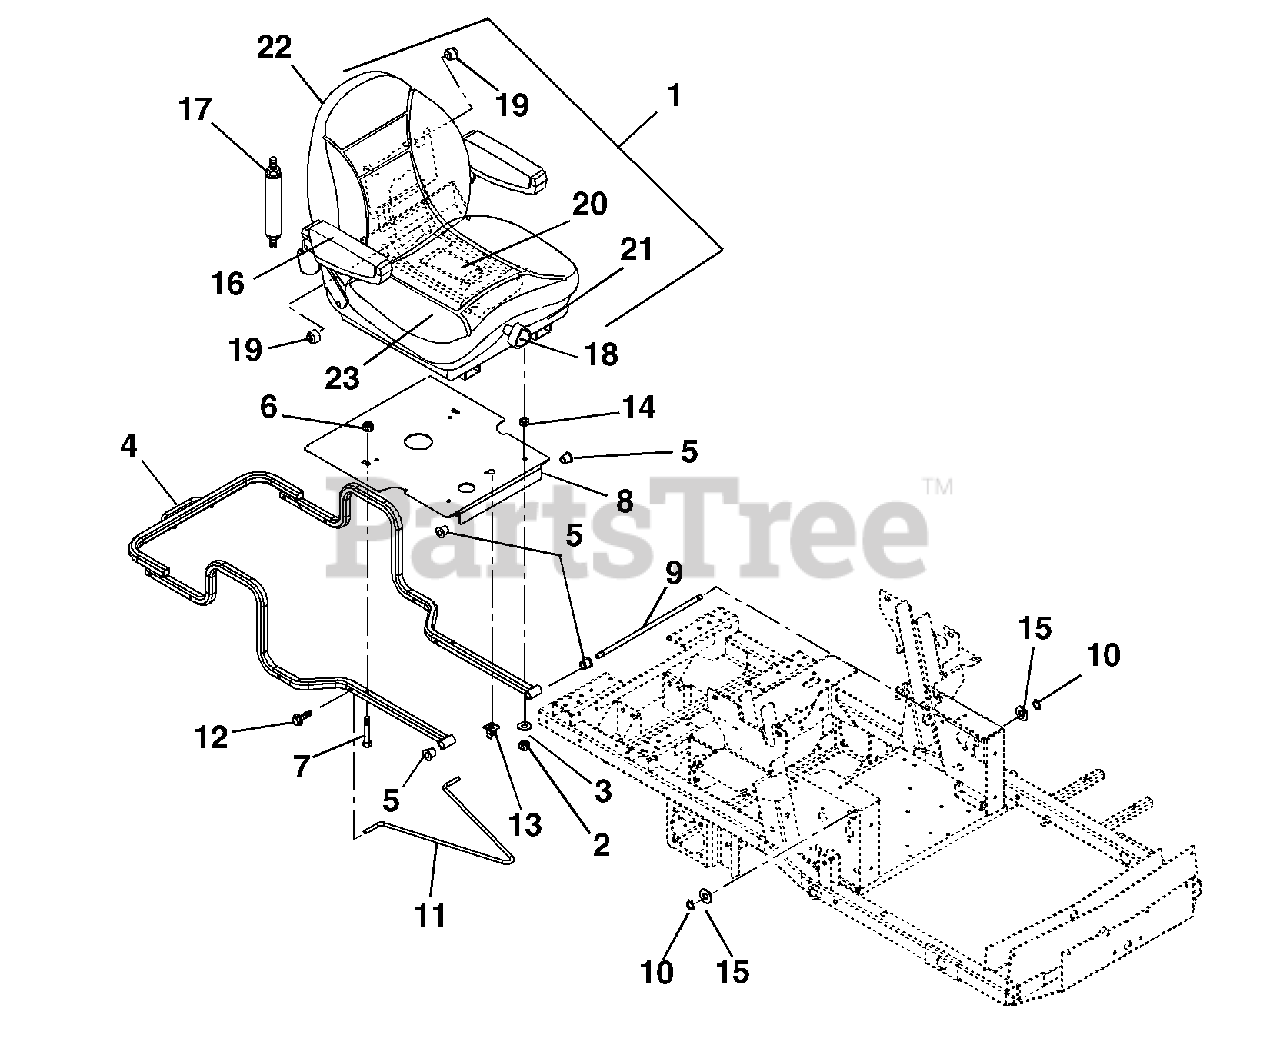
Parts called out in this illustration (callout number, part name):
1	Seat-Suspension
2	Nut-Locking-Nylon M8-1.25
3	Washer-Flat-Steel .38 x .875 x .083
4	Weldment, Hood Frame
5	Bushing-Flange .515 x .750 x .745 x 1.00
6	Nut-Locking-Top-Flange .38-16
7	Bolt-Rib Neck .38-16 x 1.50
8	Weldment, Seat Pivot Mount
9	Rod-Seat Frame Pivot
10	Ring-Retaining-External .500 x .050
11	Rod-Prop
12	Screw-Tapping .25-20 x .50 Hex Washer Head
14	Bushing-Sleeve .377 x .624 x .235
15	Washer-Flat-Steel .531 x 1.06 x .095
16	Kit-Arm Pad (1 per bag)
17	Kit-Damper w/Hardware
18	Kit-Knob (1 per bag)
19	Kit-Roller (4 per bag)
20	Kit-Spring/Cable Milsco Seat (1 per bag)
21	Kit-Adjuster (1 per carton)
22	Kit-Seatback
23	Kit-Cushion (1 per carton)
